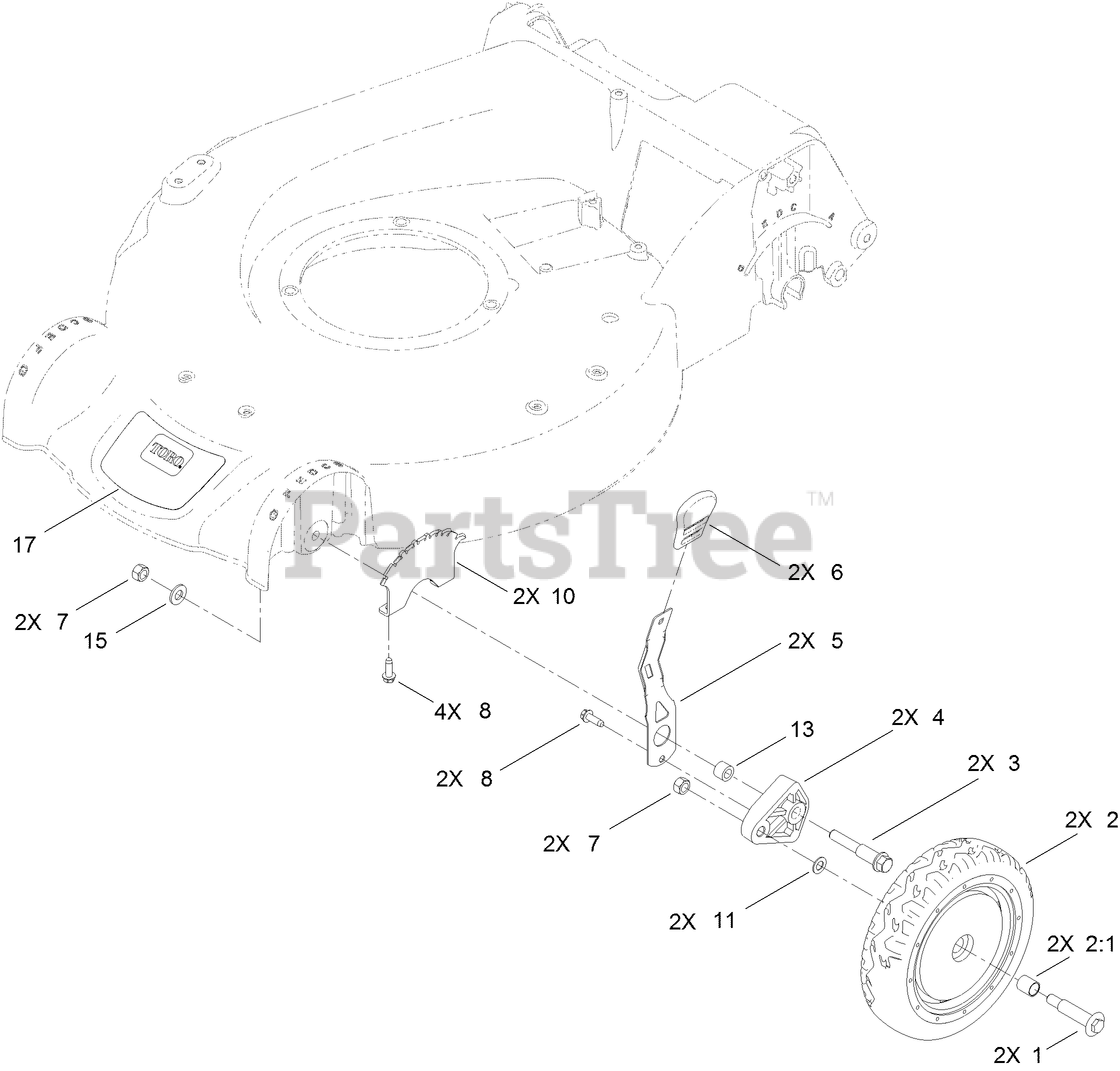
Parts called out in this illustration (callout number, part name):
1	BOLT-SHOULDER
2	WHEEL ASM
2:1	BUSHING
3	SCREW-SHOULDER
4	ARM-PIVOT
5	ARM-SPRING
6	KNOB-HOC
7	LOCKNUT
8	SCREW-HWHTF
10	PLATE-HOC
11	WASHER
13	SPACER-WHEEL
15	WASHER-FLAT
17	DECAL-HOUSING
